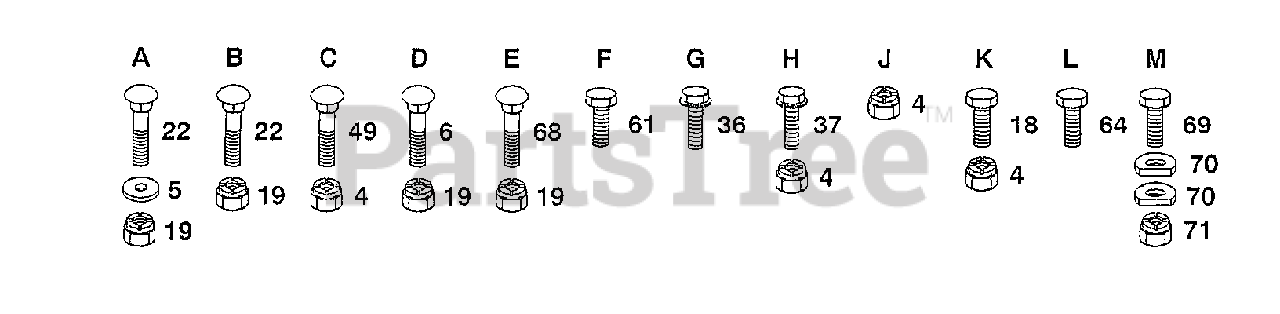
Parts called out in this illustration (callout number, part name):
5	WASHER M
6	BOLT
22	BOLT
36	SCREW
37	SCREW
49	BOLT
61	BOLT
64	BOLT.3/8-14X1.25
69	BOLT LT
70	WASHER T
